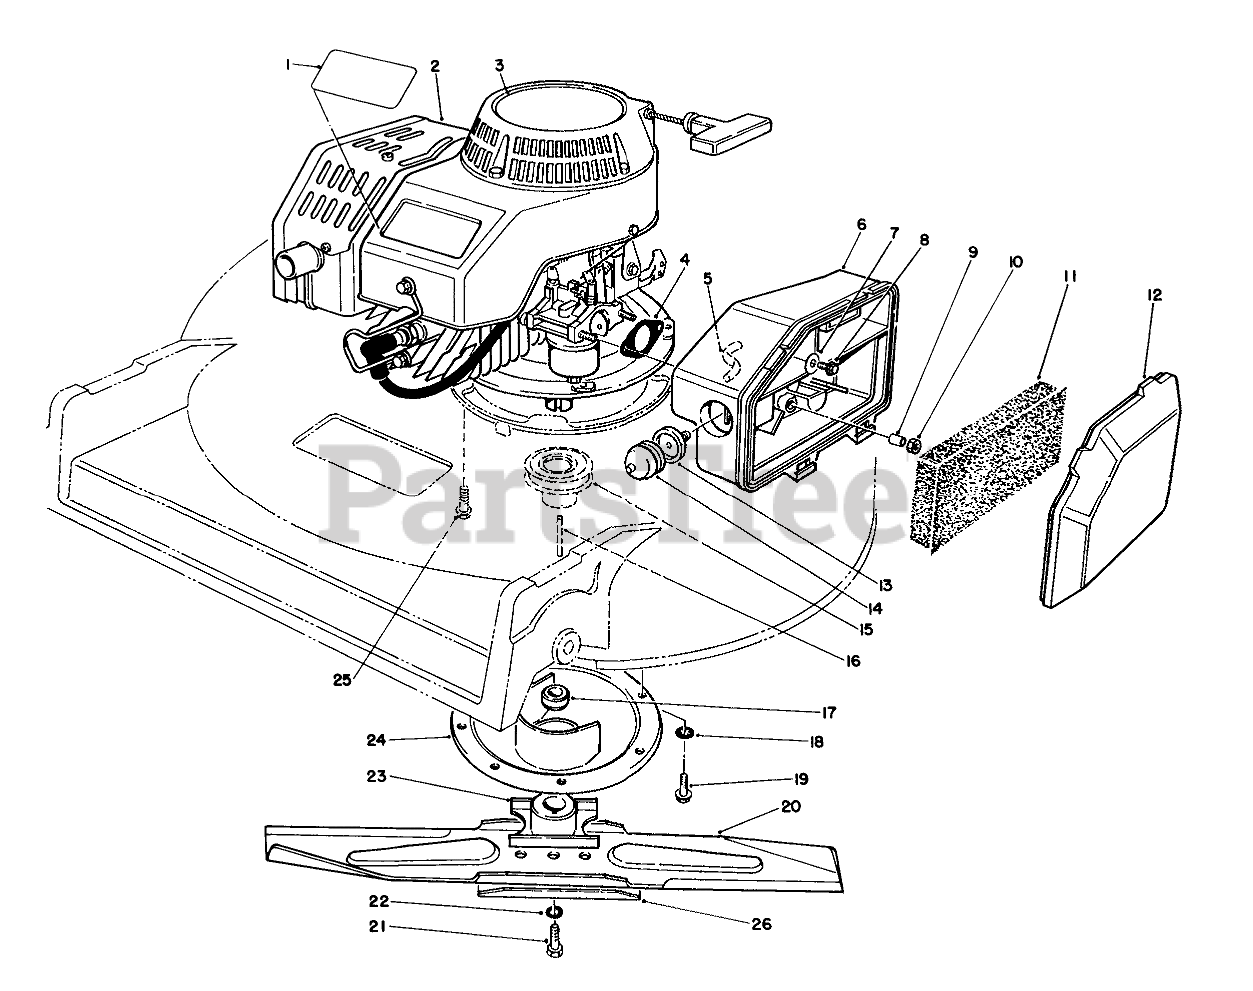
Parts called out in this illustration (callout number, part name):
1	DECAL - PROLINE
2	ENGINE ASM
3	DECAL-2 CYC RECOIL COMM
4	GASKET-AIR CLEANER
5	HOSE-PRIMER
6	BODY-AIR CLEANER
7	WASHER-FLAT
8	SCREW-HH
9	SPACER
11	ELEMENT-AIR CLEANER
12	COVER-AIR CLEANER
13	BODY-PRIMER
14	BULB-PRIMER
15	PULLEY-DRIVER
16	KEY-SQUARE
17	SPACER-BLADE RETAINER
18	WASHER-LOCK, INTERNAL
19	SCREW-HWHTF
20	Blade
21	SCREW-BLADE
22	WASHER-LOCK
23	RETAINER-BLADE
24	PROTECTOR-CRANKSHAFT
25	SCREW-HHF
26	Accelerator
